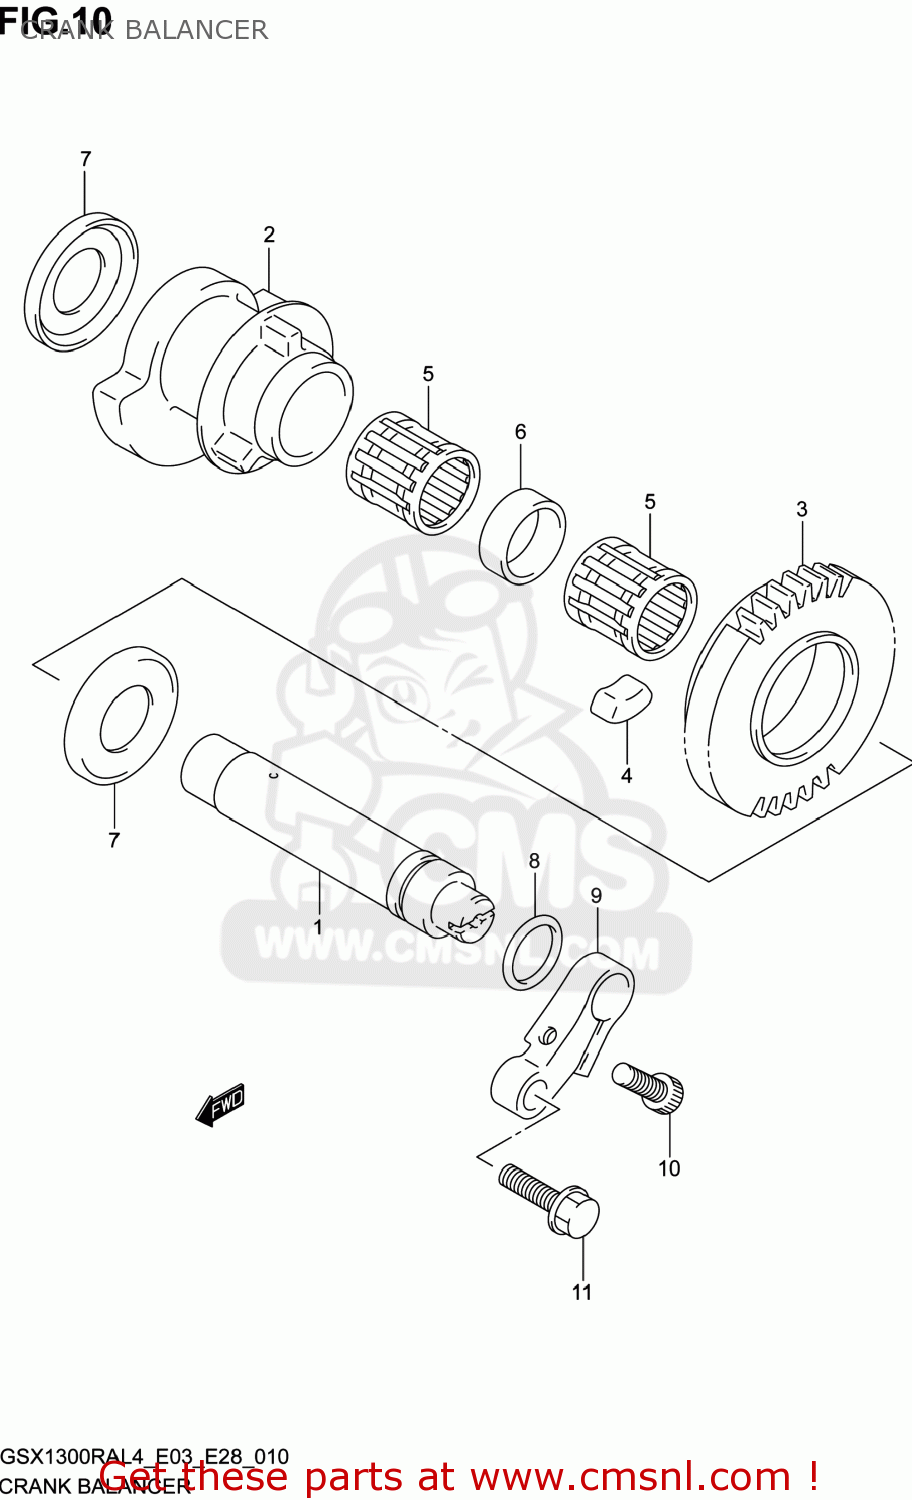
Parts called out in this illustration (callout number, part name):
1	SHAFT,CRANK BALANCER
2	BALANCER,CRANK
3	GEAR,CRANK BALANCER
4	DAMPER,BALANCER GEAR
5	BEARING(19X26X25.2)
6	SPACER(19X26X8.6)
7	WASHER
8	O RING(D:1.9,ID:16.8)
9	ARM,BALANCER SHAFT
10	BOLT
11	BOLT(6X20)
